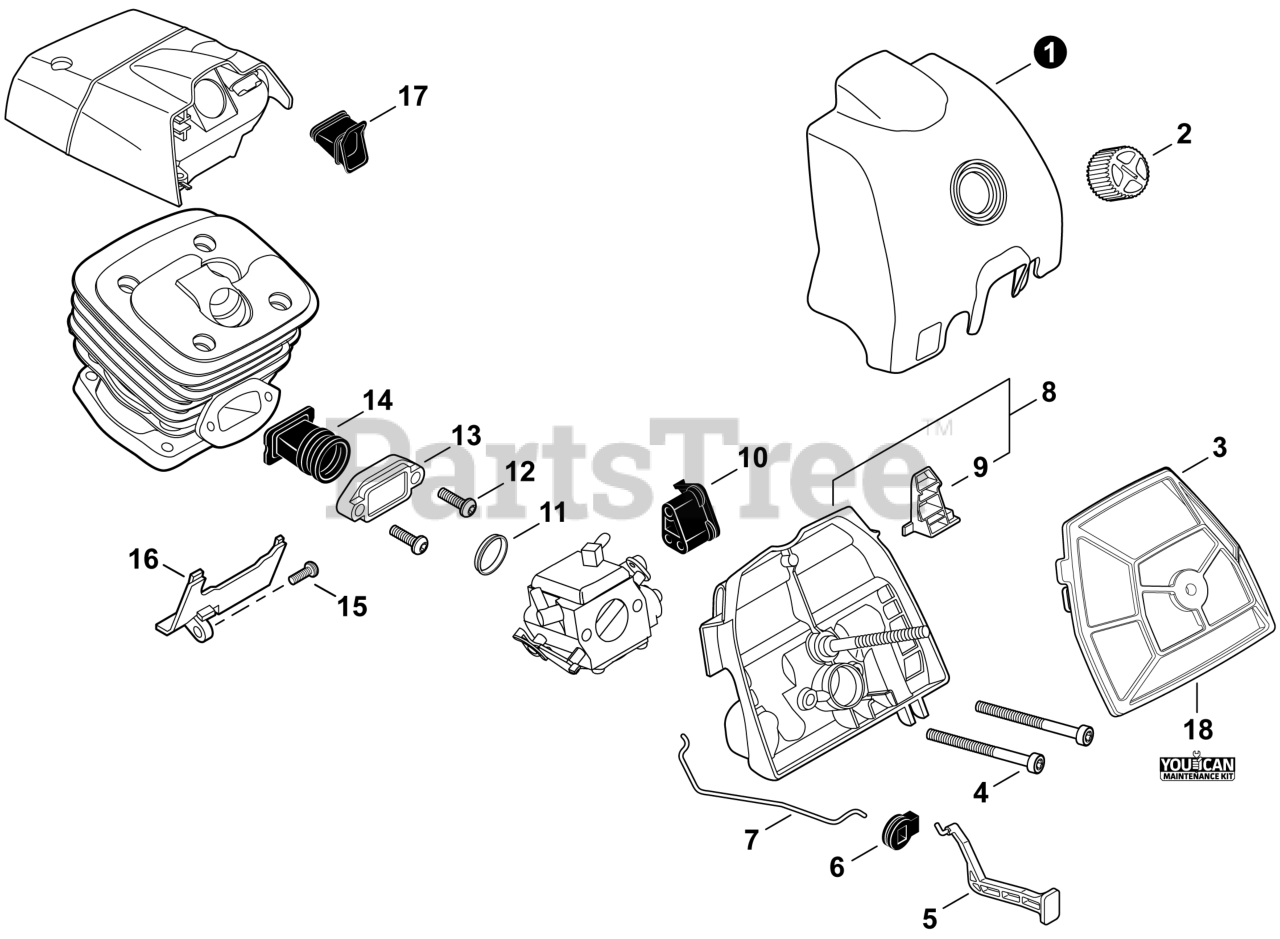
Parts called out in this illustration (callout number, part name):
1	COVER, AIR FILTER
2	KNOB, AIR FILTER COVER
3	FILTER ASSY, AIR
4	BOLT, TORX 5x50
5	ROD, CHOKE
6	GROMMET, CHOKE
7	ROD, THROTTLE
8	CASE ASSY, AIR FILTER
9	SHUTTER, AIR
10	GROMMET, NEEDLE
11	COLLAR 18.6x20.4x4
12	BOLT, TORX 5x16
13	HOLDER, BELLOWS
14	BELLOWS, INTAKE
15	BOLT, TORX 5x16
16	GUIDE, AIR
17	PIPE, INTAKE
18	TUNE-UP KIT - YOUCAN?
